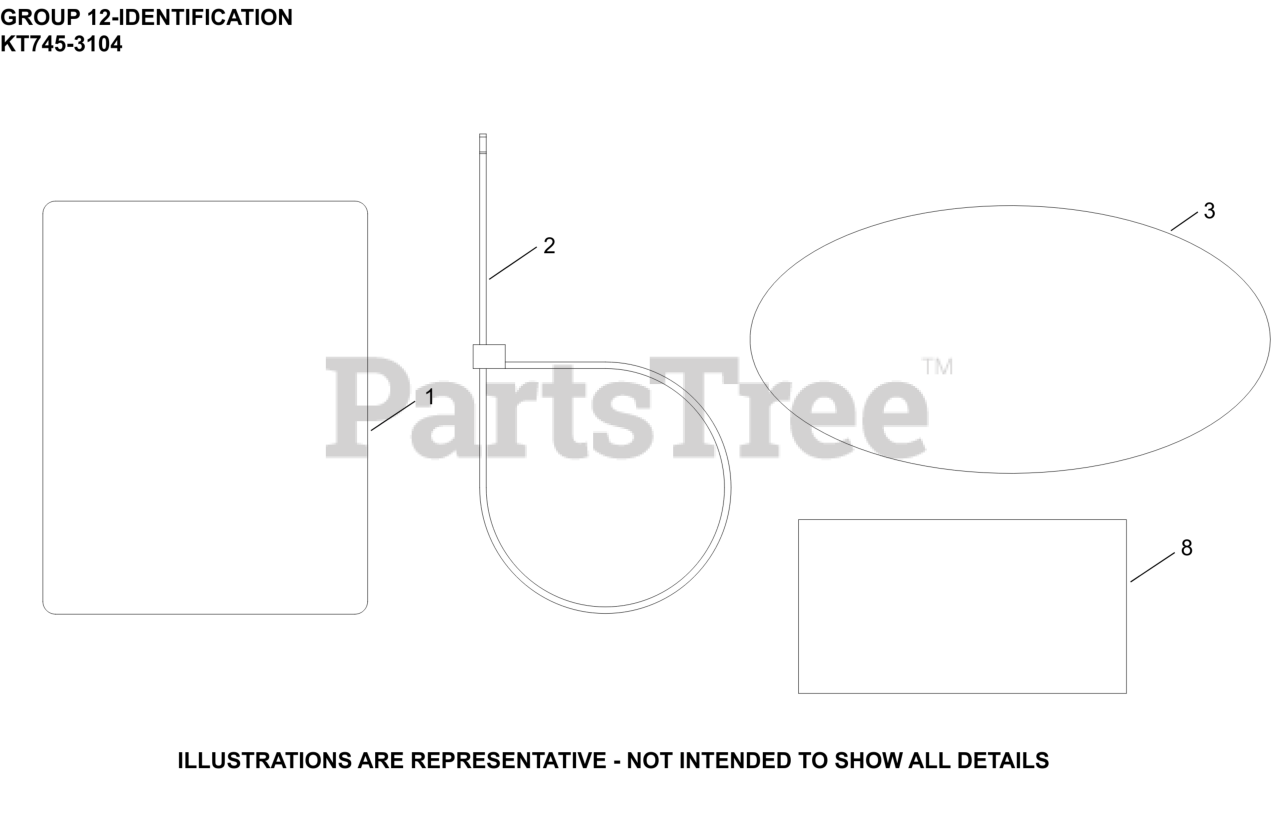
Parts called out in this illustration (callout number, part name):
1	LABEL, CLEAR LAMINATION
3	LABEL, 7000 SERIES KT745 (26 HP)
8	DECAL, USA
